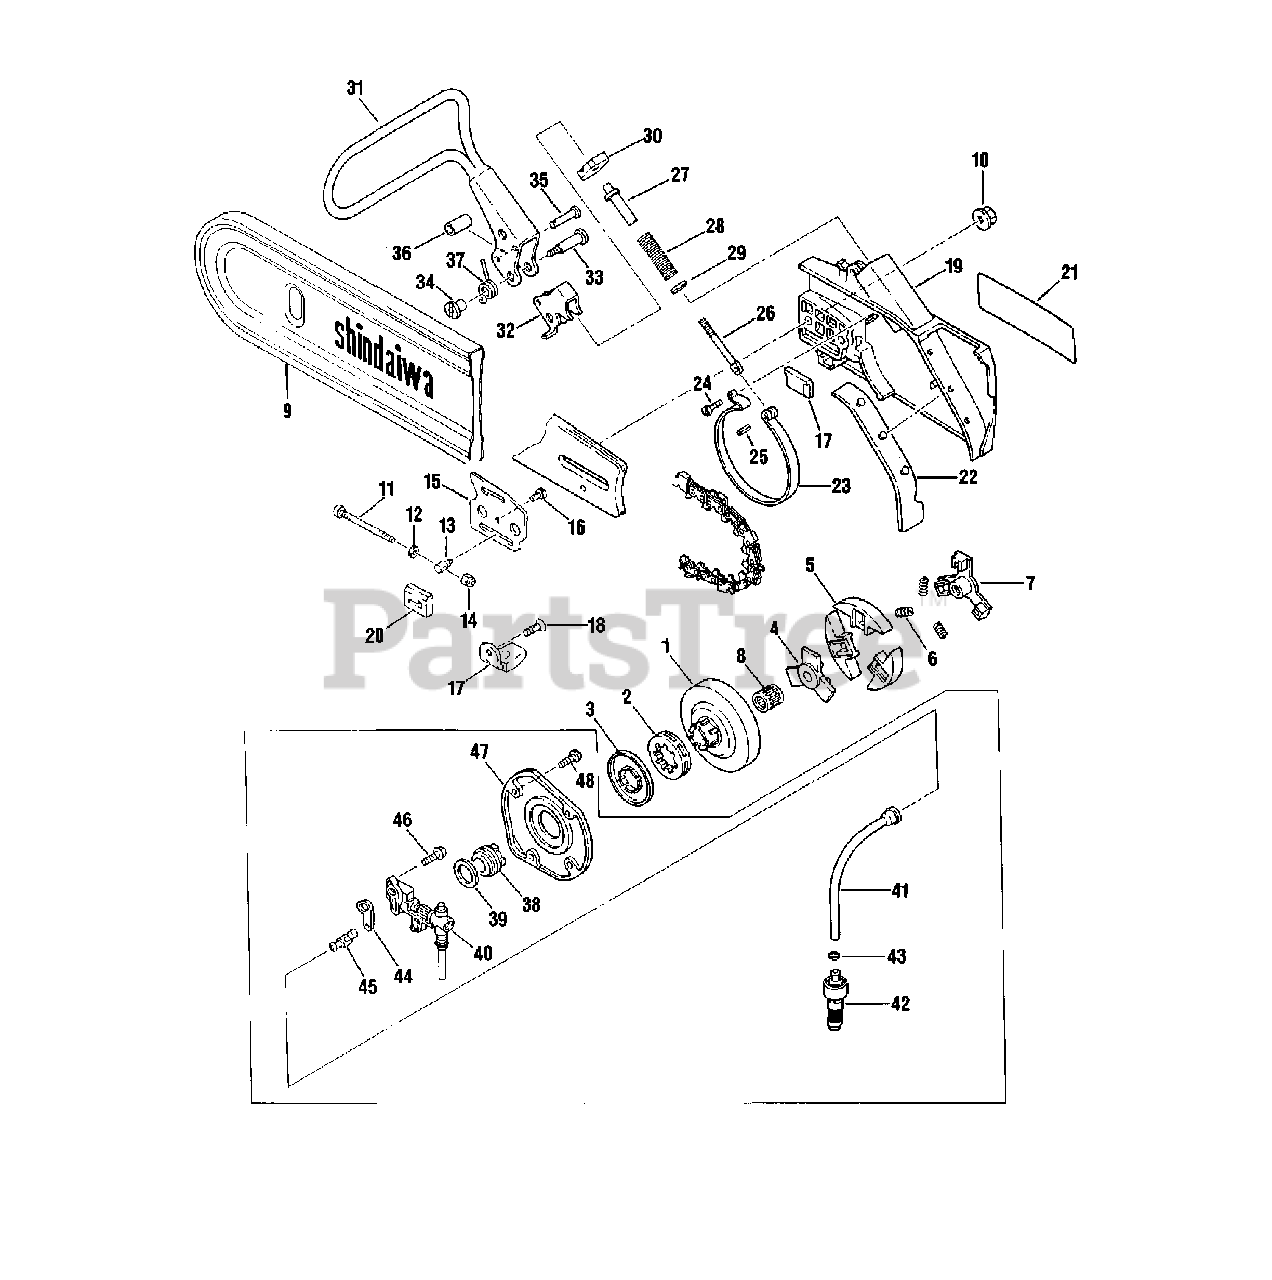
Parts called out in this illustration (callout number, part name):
1	DRUM, CLUTCH
2	SPROCKET, RIM
3	COVER, RIM
4	HUB, CLUTCH - INNER
5	SHOE, CLUTCH
6	SPRING, CLUTCH
7	HUB, CLUTCH - INNER
8	BEARING, NEEDLE
9	PROTECTOR
10	NUT
11	BAR ADJUSTING SCREW
12	WASHER, FLAT 5.5×10×0.8
13	TENSIONER, CHAIN
14	LOCKNUT
15	MOUNT GUARD
16	SCREW
17	CATCHER, CHAIN
18	SCREW - 5×12
19	CLUTCH COVER ASSY
20	GUIDE, CHAIN
21	NAME PLATE (C)
22	PROTECTOR
23	BAND, BRAKE
24	BAND BOLT
25	PIN, SPRING 4×12
26	ROD, ADJUST
27	SCREW, ADJUST
28	SPRING ,BRAKE
29	WASHER
30	BLOCK
31	LEVER, BRAKE
32	INNER LEVER
33	BOLT, LEVER
34	NUT, LEVER
35	PIN, STOPPER
36	CUSHION
37	LEVER, SPRING
38	GEAR
39	THRUST PLATE
40	OIL PUMP ASSY
42	FILTER, OIL
43	CLIP, OIL FILTER
44	GASKET, OIL PUMP
46	SCREW M4×16
47	COVER, PUMP
48	SCREW
